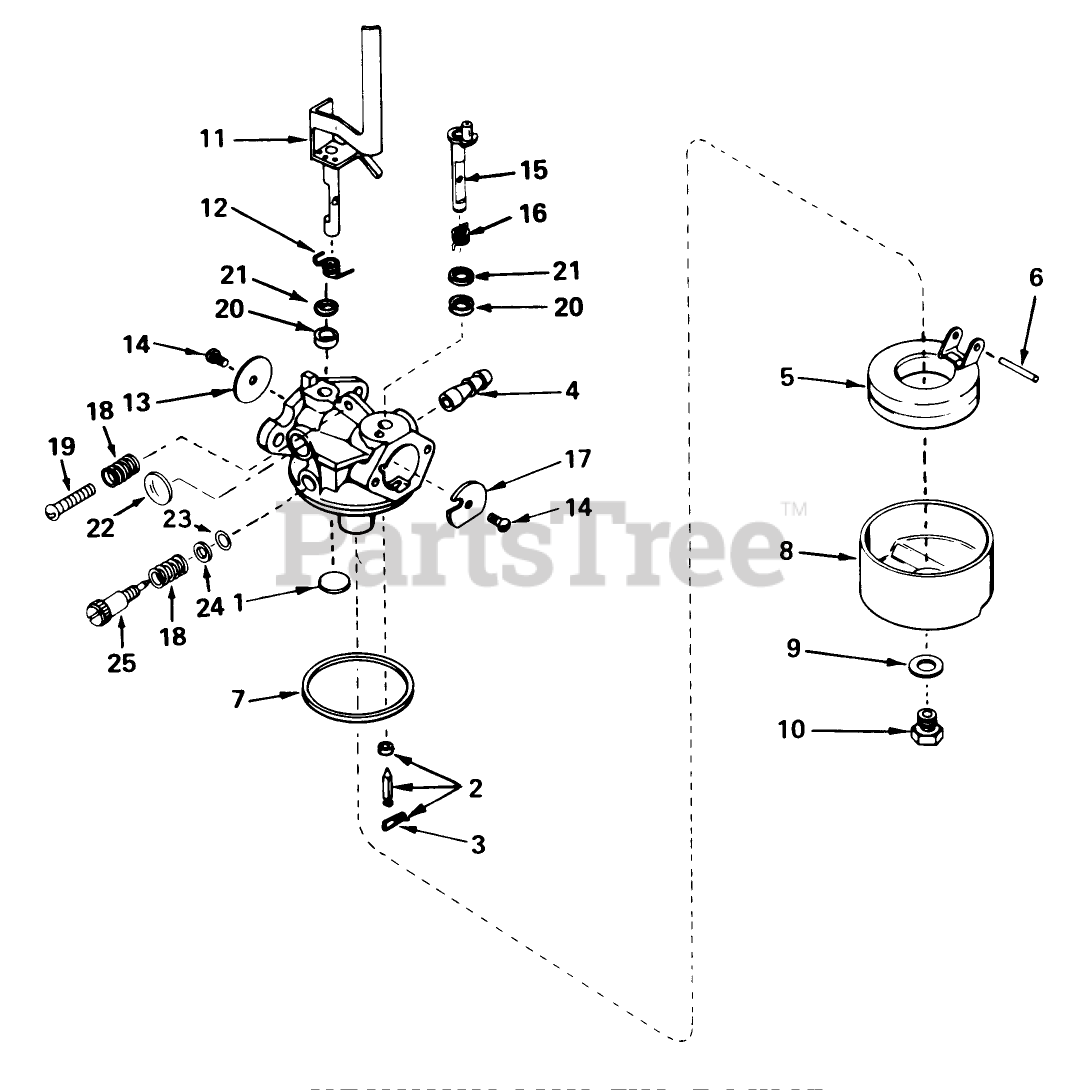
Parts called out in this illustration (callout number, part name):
1	Plug-Welch, Atmospheric Vent
2	Inlet Needle, Seat Clip Assy. (Incl. No. 13)
3	Clip-Spring
4	Fuel Fitting
5	Float
6	Shaft-Float
7	O Ring-Bowl, Float
8	Bowl Float
9	Gasket-Bowl
10	Nut, Float Bowl
11	Shaft Lever Assy., Throttle
12	Spring-Return, Throttle
13	Shutter-Throttle
14	Screw-Shutter
15	Shaft Lever Assy., Choke
16	Spring, Choke Return
17	Shutter-Choke
18	Spring-Tension
19	Screw-Throttle Crack Screw / Idle Speed
20	Seal-Dust
21	Washer-Seal, Dust
22	Plug-Welch, Idle Mixture Well
23	ORing
24	Washer
25	Screw Main Adjustment
